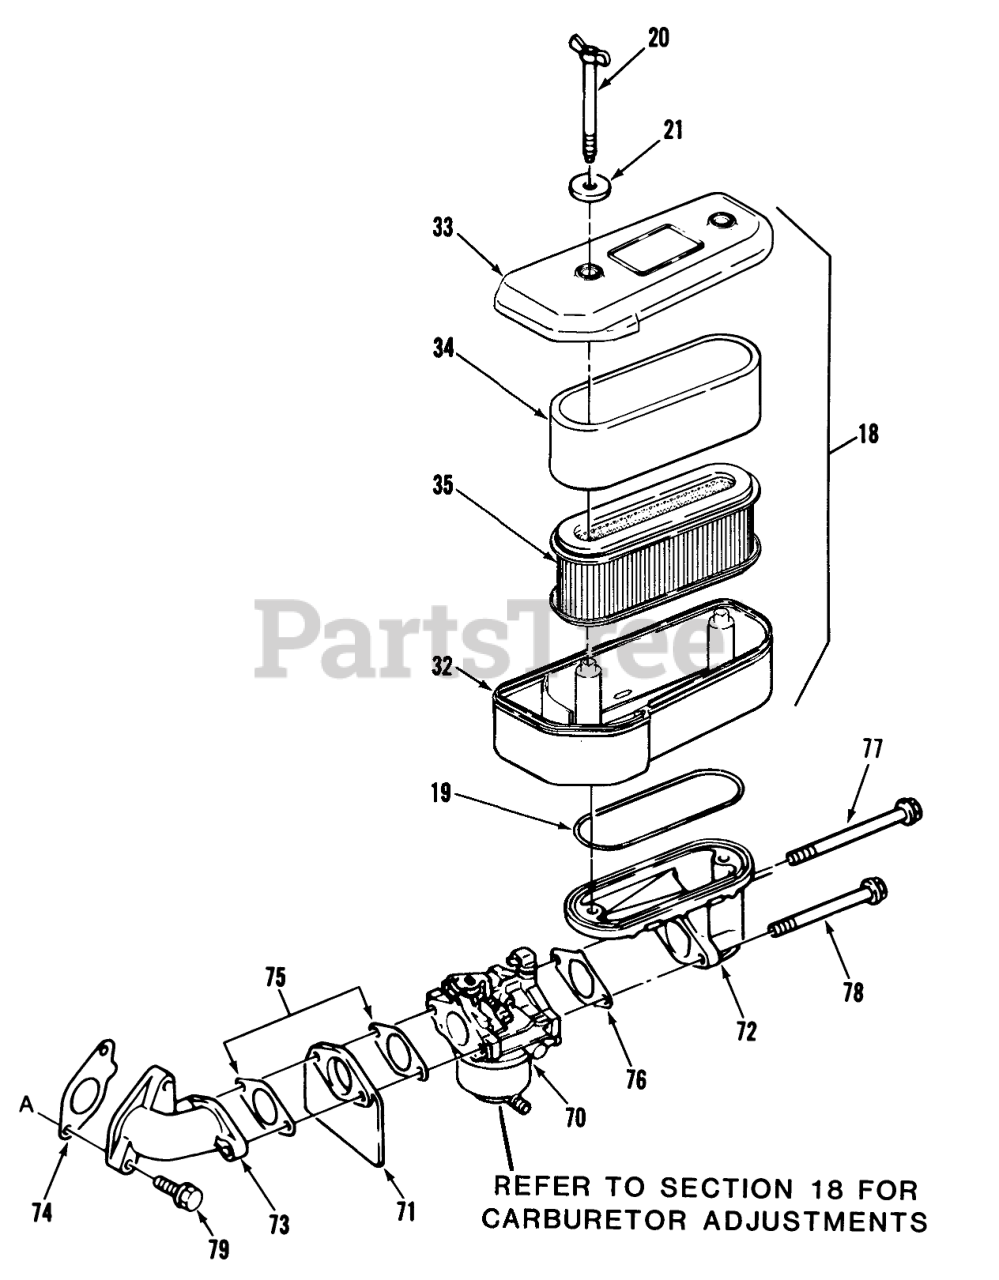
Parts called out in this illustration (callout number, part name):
18	Air Filter Assy (includes items 32, 33, 34 & 35)
19	GASKET
21	WASHER
32	Air Filter Case
33	CAP-AIR FILTER
34	ELEMENT-AIR CLEANER
35	AIR CLEANER ELEMENT
70	Carburetor Assy AS-13
70	Carburetor Assy CS-13
70	Carburetor Assy BS-13 See section 9-6 for complete parts breakdown
71	INSULATOR
72	MANIFOLD INTAKE
73	MANIFOLD INTAKE
74	GASKET
75	GASKET
76	GASKET
79	BOLT, FLANGED 8X25
